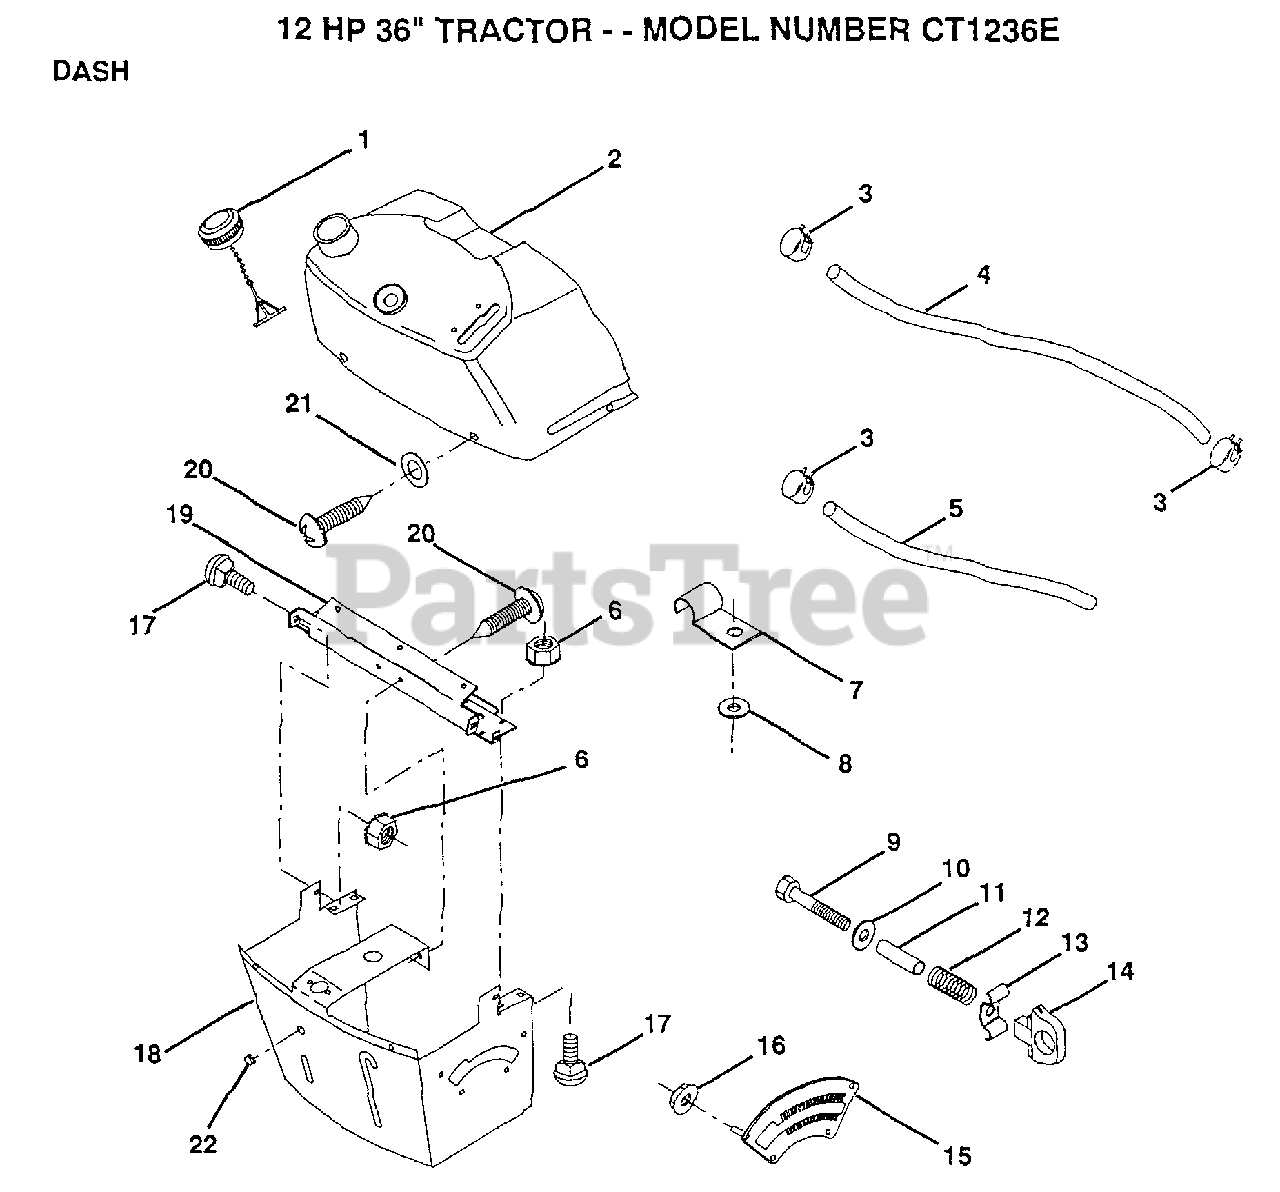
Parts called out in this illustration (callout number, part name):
3	HOSE CLAMP
5	FUEL LINE T
6	NUT
7	CLIP T
8	WASHER PM
9	BOLT
11	SPACER SPLIT
12	SPRING M
13	"KNOB,HGT RETAINER"
14	KNOB
15	ADJUSTER QUAD
16	NUT
17	BOLT
18	SUPT ASSY DASH
19	CROSS BRACE
22	PLUG DOME
